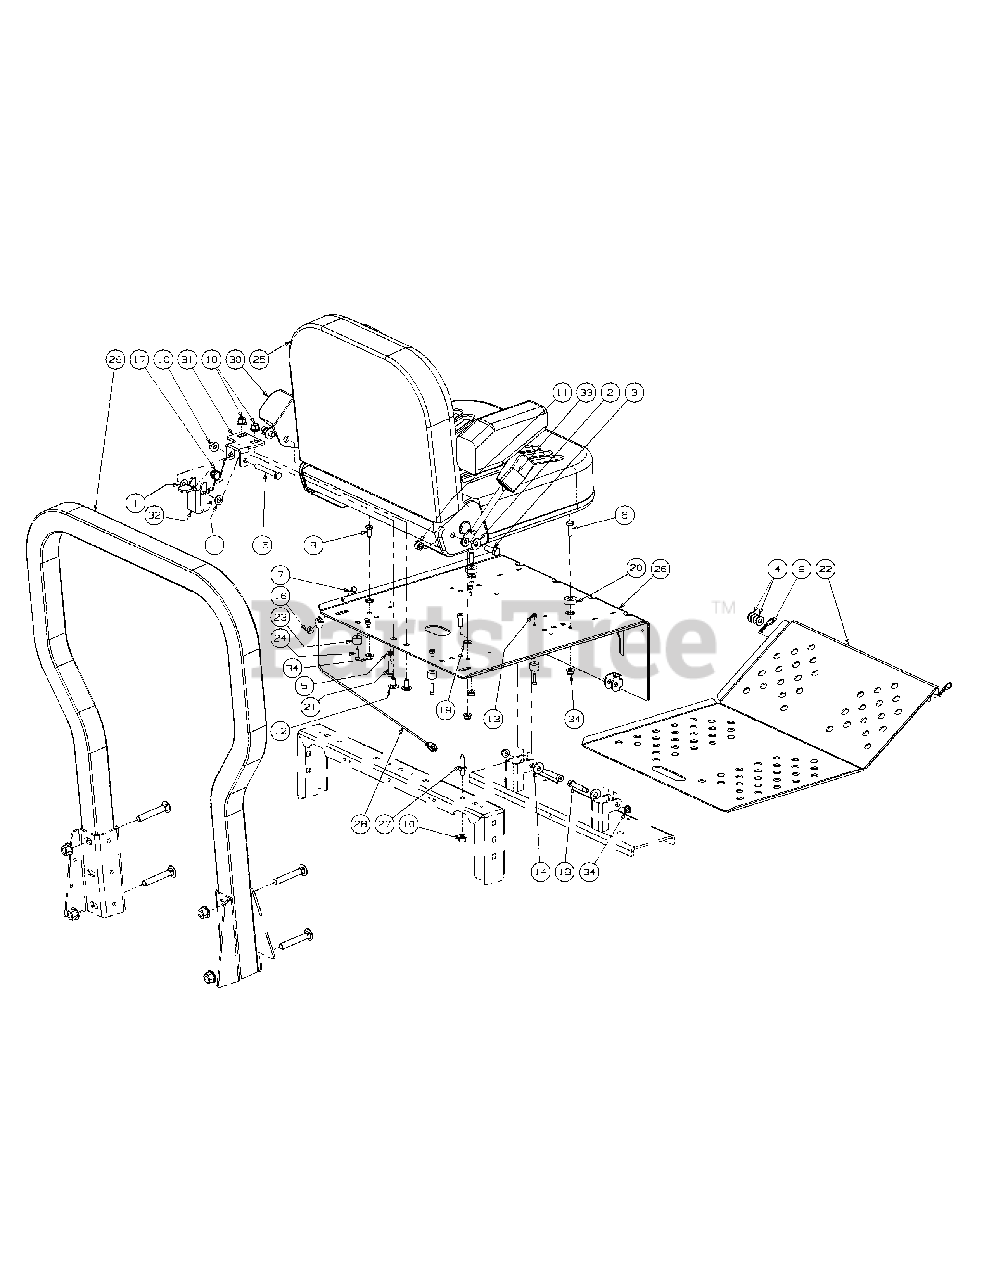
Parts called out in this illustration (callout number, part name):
1	Flat Washer, 3/8 Nylon
2	Flat Washer, 3/8
3	Hex Cap Screw, 7/16-14 x 1.00
5	Washer, .390 ID x 1.0 OD x .180
6	Hex Head Capscrew, 5/16-18 x 1.00
7	Screw, Hex, Cap, 1/4-20 x .75
8	Hex Head Capscrew, 5/16-18 x .75
9	Hair Pin, 3/8-1/2
10	Flange Lock, Hex Nut, 3/8-16
11	Nylock Nut, 7/16-14
12	Carriage Bolt, 3/8-16 x .75 Long
13	Nut, #10-24, Nylon Lock
14	Flat Washer, .406 ID, 1.0 OD, .105
15	Hex Cap Screw 3/8-16 x 2.75
16	Lock Nut, 1/4-20
17	Deck Lift Spring, Left Hand
18	Shoulder Bolt, .375 x 1.50
19	Push Retainer, 5/16
20	Spacer .406 ID x 1.0 OD
21	Self Tapping Screw 5/16-18 x 1.00
22	Floor Panel Assembly
23	Rubber Stop with Washer
24	Standard Cap Screw, #10-24 x .75
25	Seat includes:
26	Seat Plate Assembly
27	Adjustable Stud
28	Cable Support
29	Rops Assembly includes:
33	Seatbelt Buckle
34	Nut, 5/16-18, Flangelock
